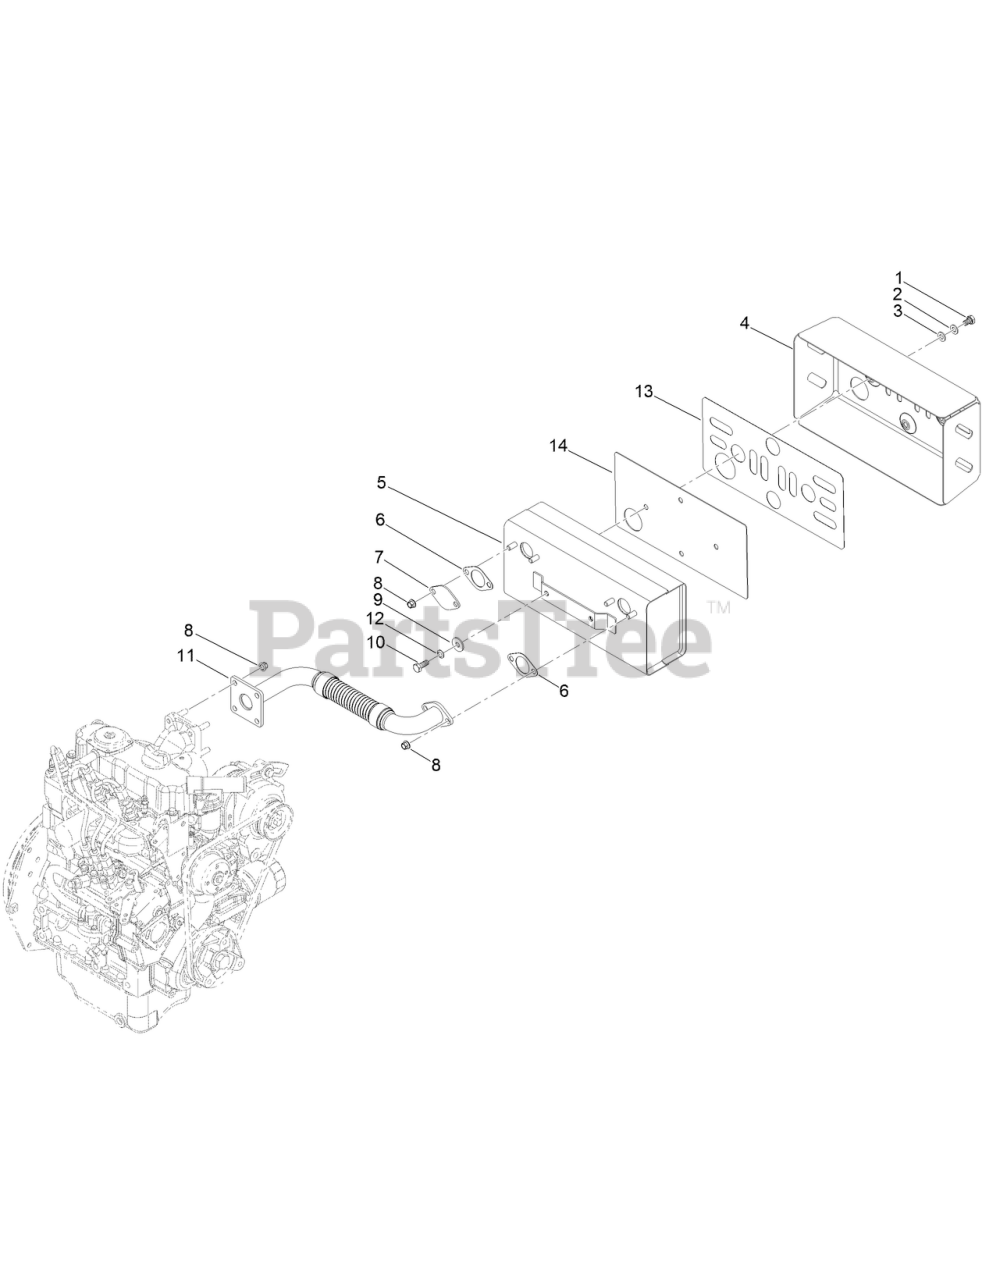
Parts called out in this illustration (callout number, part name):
2	WASHER
3	WASHER
4	COVER, MUFFLER
5	MUFFLER
6	GASKET, MUFFLER
7	FLANGE, MUFFLER
9	WASHER
11	MANIFOLD, EXHAUST
12	WASHER
13	TAPE, MUFFLER
14	PLATE, SPACER-MUFFLER
